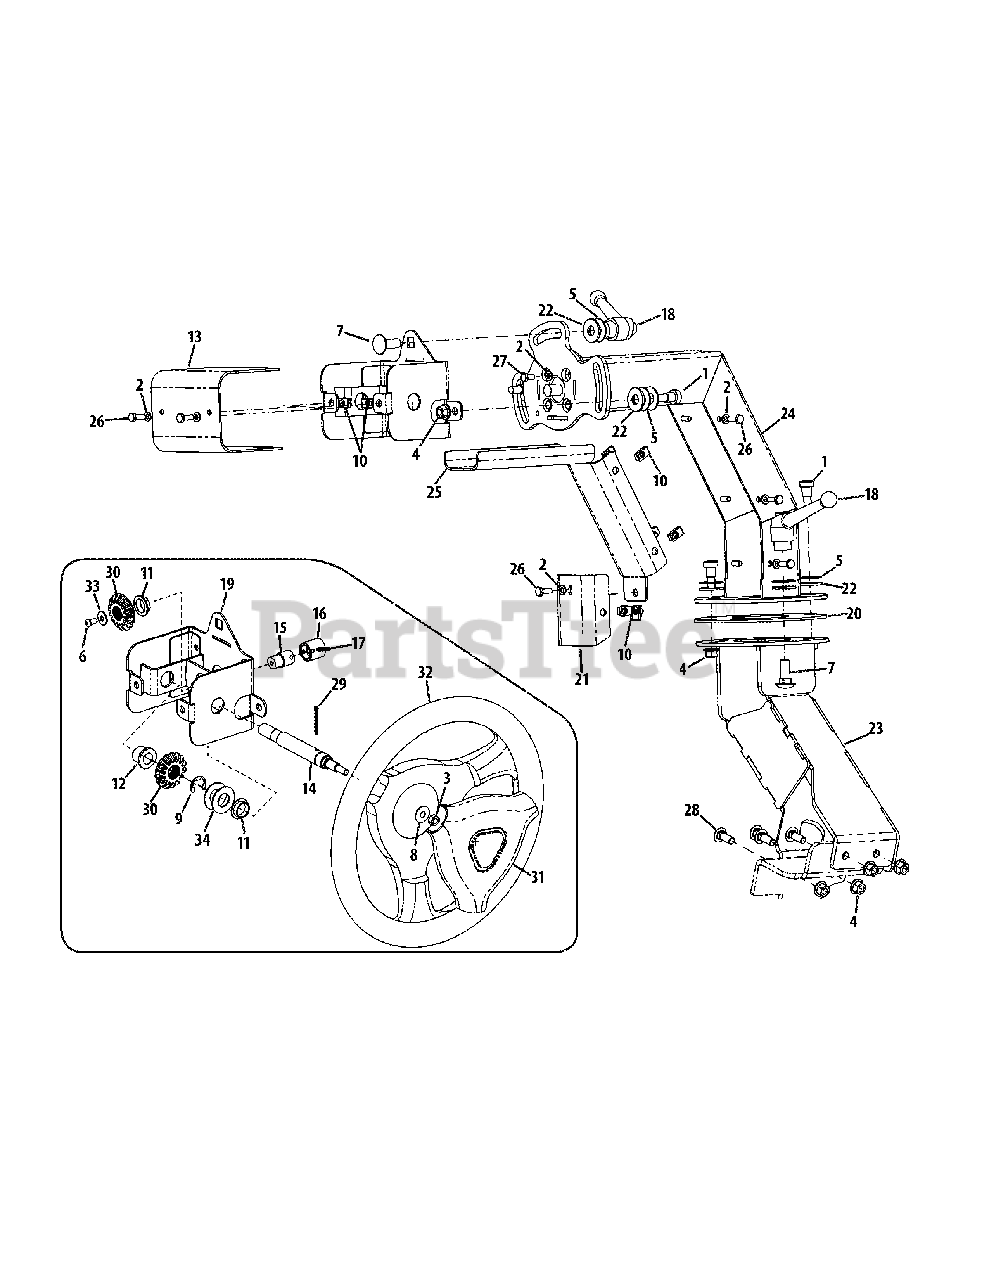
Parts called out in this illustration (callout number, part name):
1	Shoulder Bolt, 3/8-16 x .495 x .500
2	Lock Washer, .250 x .489 x .110
3	Nut, 5/16-24
4	Flange Counter Lock Nut, 3/8-16
5	Washer, .533 x 1.25 x .058
6	Screw, 1/4-20 x .500
7	Carriage Bolt, 1/2-13 x 1.25
8	Bell Washer, .325 x .930 x .045
9	Retainer Clip
10	U-Nut, 1/4-20
11	Flange Bearing, .752 x 1.25 x .305
12	Flange Slv. Bearing, .630 x .875 x .75
13	Box Steering Cover
14	Steering Shaft
15	Valve Steering Shaft
16	Steering Valve Spline Hub
17	Spirol Pin, 3/16 x 1.0
18	Steering Adjust/Lock Lever
19	Steering Box Housing Assembly
20	Wear Swing Plate
21	Steering Column Cover
22	Washer, .531 x 1.250 x .100
23	Base Column Assembly
24	Upper Steering Column Assembly
25	Upper Steering Column Cover
26	Hex Screw, 1/4-20 x .75
27	Hex Screw, M6-1.00 x 14
28	Carriage Bolt, 3/8-16 x 1.00
29	Cotter Pin, 1/8 x 1.25
30	Splined Bore Miter Gear
31	Steering Wheel Cover
32	Steering Wheel
33	Flat Washer, .28 x .74 x .063
34	Flat Washer, .76 x 1.49 x .06
